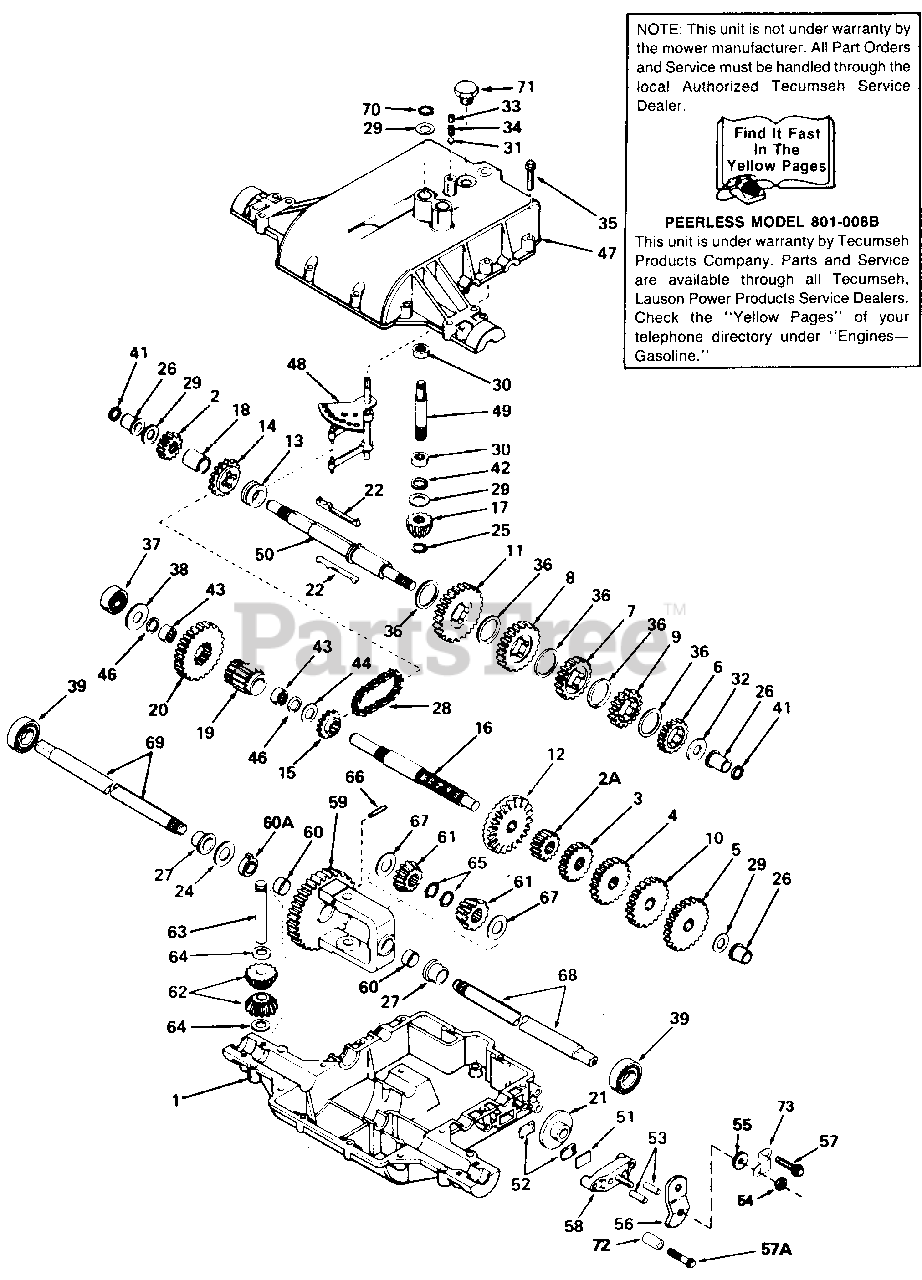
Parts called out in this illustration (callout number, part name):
1	Case: Transaxle
2	Gear: Spur (15 teeth)
2A	Gear: Spur (12 teeth)
3	Gear: Spur (20 teeth)
4	Gear: Spur (25 teeth)
5	Gear: Spur (30 teeth)
6	Gear: Spur (20 teeth)
7	Gear: Spur (25 teeth)
8	Gear: Spur (30 teeth)
9	Gear: Spur (22 teeth)
10	Gear: Spur (28 teeth)
11	Gear: Spur (37 teeth)
12	Gear. Bevel (42 teeth)
13	Collar: Shift
14	Sprocket (18 teeth)
15	Sprocket (9 teeth)
16	Shaft: Counter
17	Bevel Pinion: Input
18	Spacer
19	Pinion: Output
20	Gear: Output
21	Disk: Brake
22	Key
24	Washer
25	Ring: Retaining
26	Bushing: Flanged
27	Bushing: Flanged
28	Chain: Roller
29	Washer: Thrust
30	Bearing: Needle
31	Ball: Steel
32	Washer: Thrust
33	Screw: Set: 3/8-16 x 3/8
34	Spring
35	Screw: Hex Hd. Thread Forming: 1/4-20 x 11/4
36	Washer: Thrust
37	Bearing: Ball
38	Washer: Flat
39	Bearing: Ball
41	Ring: Square Cut
42	Ring: Square Cut
43	Bearing: Needle
44	Washer: Flat
46	Ring: Square Cut
47	Cover: Transaxle
48	Rod & Fork Ass'y.: Shift
49	Shaft: Input
50	Shaft: Brake
51	Plate: Brake Pad
52	Pad: Brake
53	Pin: Dowel
54	Locknut: 5/16-24
55	Washer: Flat
56	Lever: Brake
57	Screw: Hex Hd. Thread Forrning: 1/4-20 x 11/4
57A	Screw: Hex Hd. Thread Forrning: 1/4-20 x 21/4
58	Holder: Brake Pad
59	Gear Ass'y.: Differential
60	Bushing
60A	Bushing
61	Gear: Bevel
62	Pinion: Bevel
63	Pin: Drive
64	Washer: Thrust
65	Ring: Retaining
66	Pin: Roll
67	Washer: Thrust
68	Axle (15-1/4" Long)
69	Axle (13-3/8" Long)
70	Ring: Retaining
71	Plug: Hex Hd.: 9/16-18 Thread
72	Spacer
73	Bracket: Brake Lever
